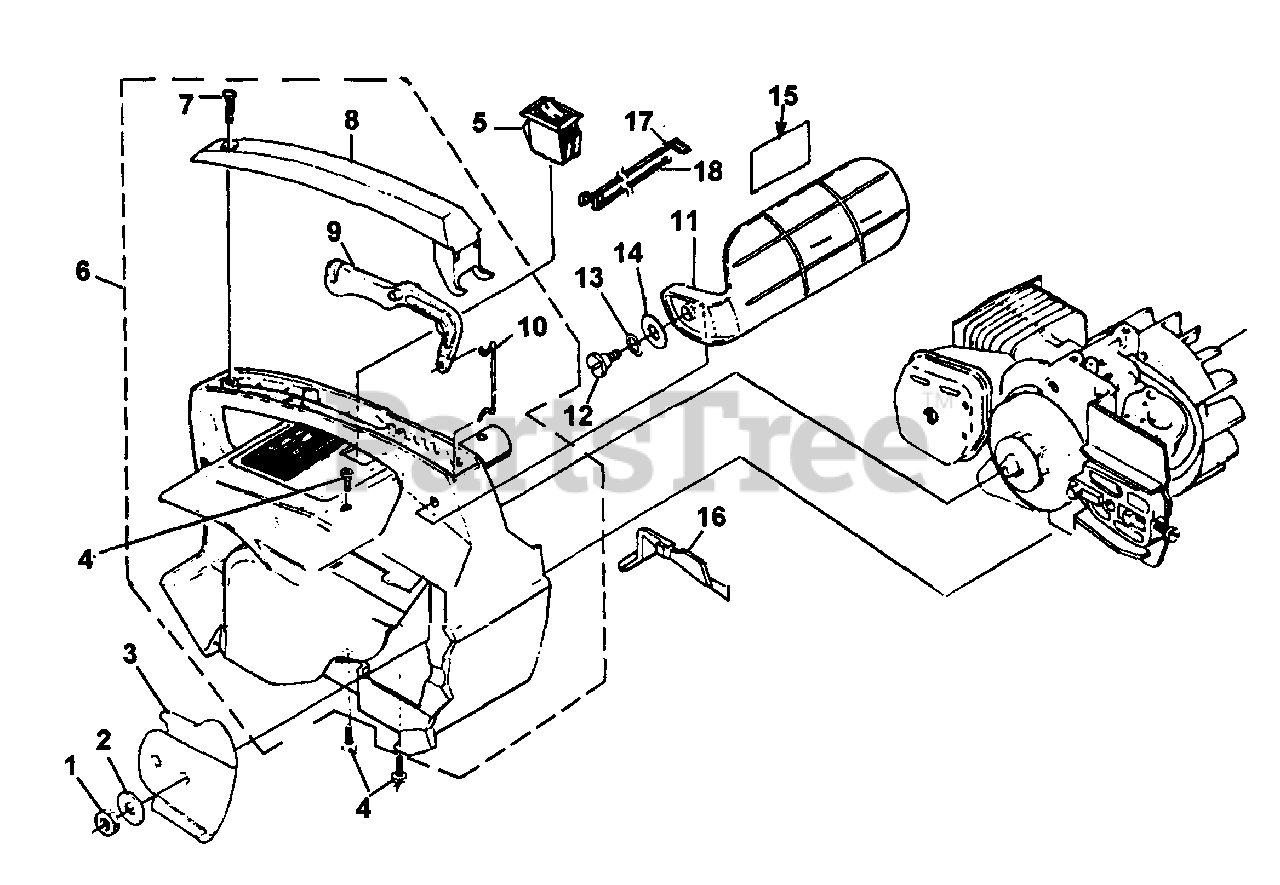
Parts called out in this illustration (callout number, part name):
1	NUT, GUIDE BAR
2	WASHER, FLAT
3	PLATE, GUIDE BAR
4	SCREW, PAN HEAD (10-24 x 3/4")
5	SWITCH, ROCKER
6	HOUSING ASSY. ENGINE
7	SCREW, PAN HEAD (#10 x 5/8")
8	COVER, HANDLE
9	TRIGGER
10	ROD, THROTTLE
11	HAND GUARD ASSY.
12	SCREW, SHOULDER (#10 x .560)
13	WASHER, CURVED SPRING
14	WASHER, FLAT
15	DECAL, HAND GUARD
16	COVER, AIR FILTER
17	LEAD, WIRE
18	LEAD, WIRE
